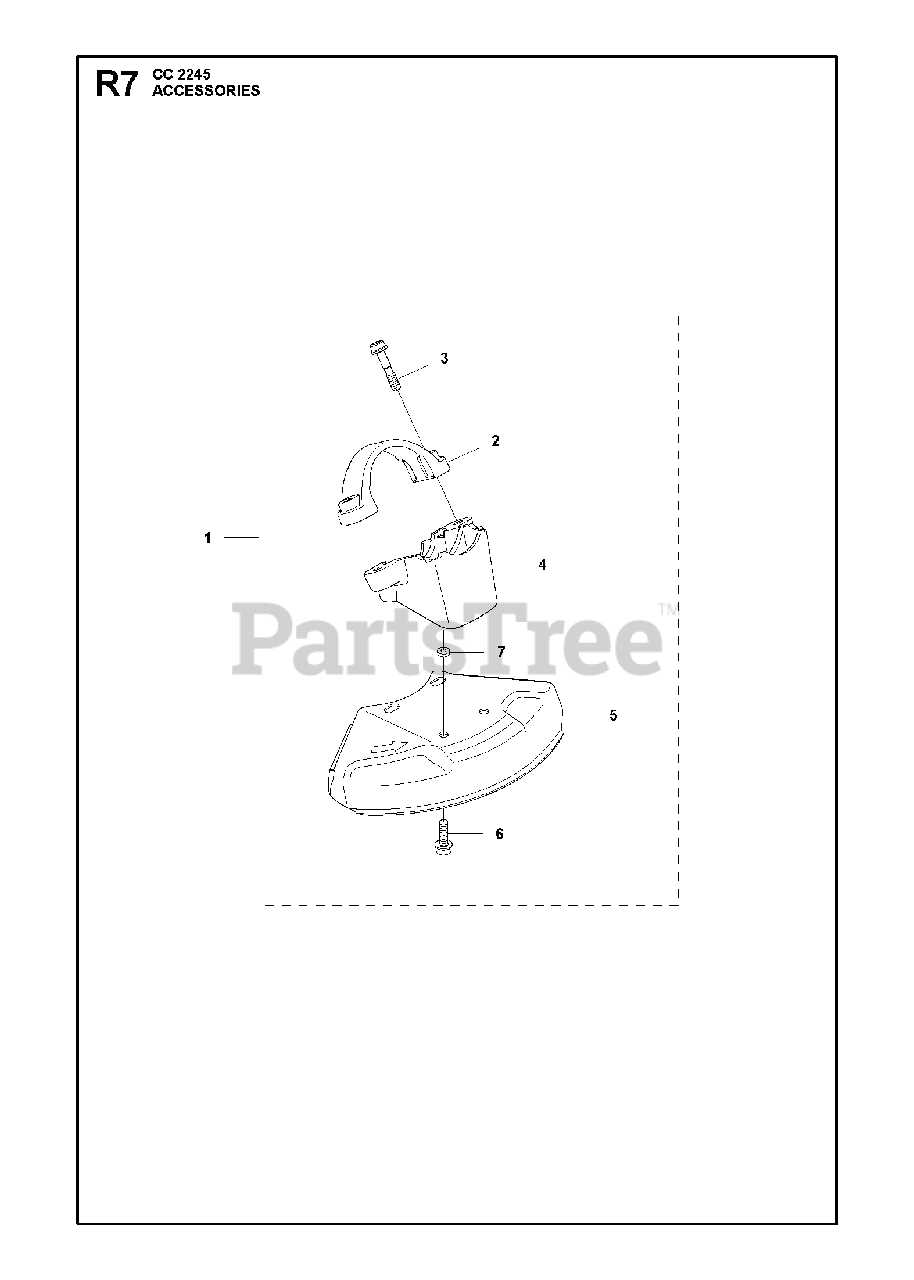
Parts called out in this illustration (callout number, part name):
1	TRIMMER GUARD ASSY
2	CLAMP
3	SCREW IHSCFMO
4	ADAPTER
5	RP BLADE GUARD
6	SCREW
7	LOCKING NUT
